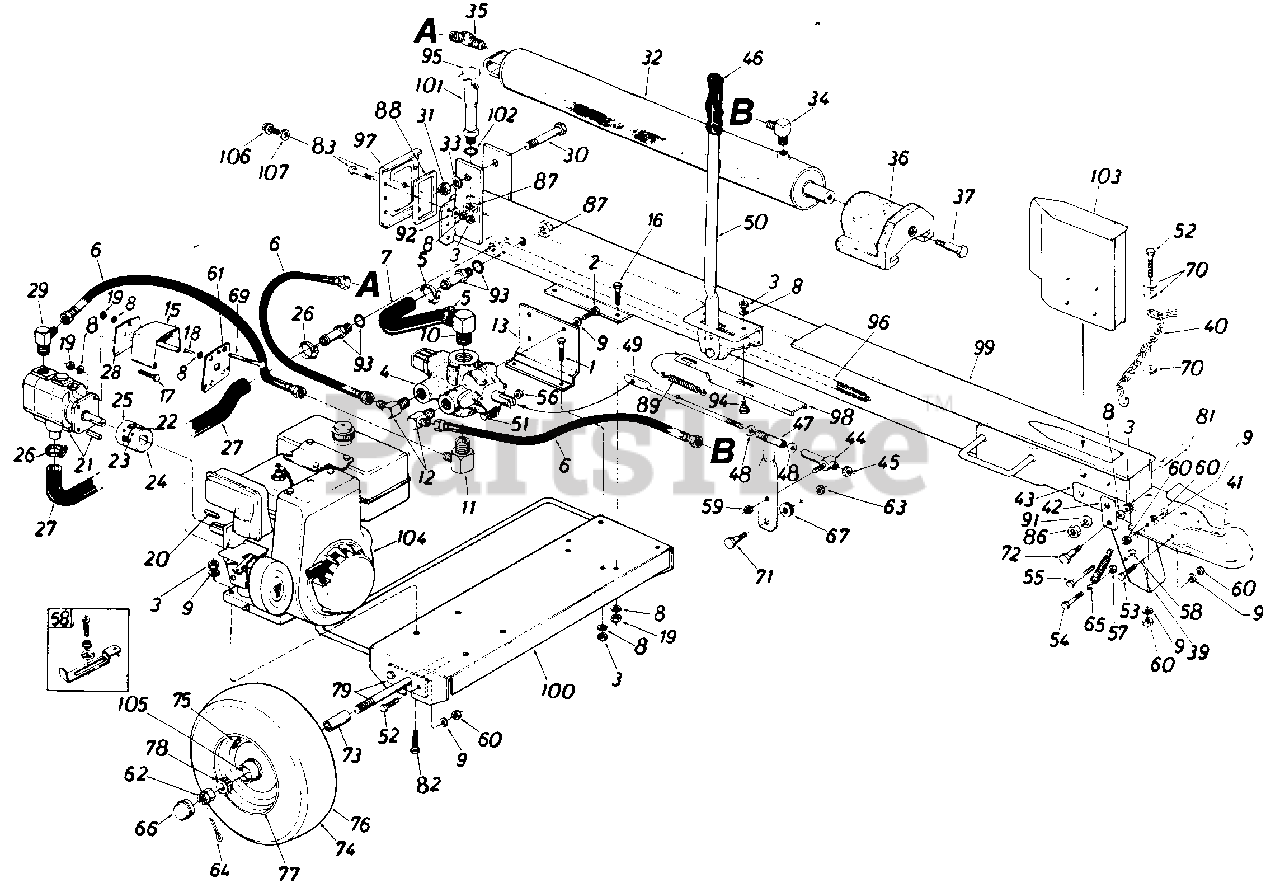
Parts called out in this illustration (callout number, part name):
1	Hex Bolt 5/16-18 x .75" Lg.
2	Hex Bolt 3/8-16 x .50" Lg.
3	Hex Nut 5/16-18 Thd.
4	Control Valve 400
5	Hose Clamp 5/8"
6	H igh Pressure Hose Ass'y. .38" I.D.
7	Return Hose-Valve to Tank 3/4" I.D.
8	L.-Wash. 5/16" I.D.
9	L.-Wash 3/8" I D.
10	Return Elbow
11	90ø Solid Male Adapter
12	90ø Solid Male Adapter
13	Valve Mtg. Plate
15	Coupling Shield
16	Hex Bolt 5/16-24 x 1.00" Lg.
17	Hex Bolt 5/16-24 x .75" Lg.
18	Hex Bolt 5/16-24 x .62" Lg.
19	Hex Nut 5/16-24 Thd.
20	Sq. Key 3/16" x 2.25" Lg.
21	PumP with Woodruff Key
22	Spider L-0-90
23	Set Scr. 1/4-20x .25" Cup
24	Coupling Half .75" I.D.
25	Coupling Half .50" I.D.
26	Hose Clamp 5/8"
27	Suction Hose 1.0" Dia.
29	90ø Solid Male Adapter
30	Hex Bolt 3/4" x 4.0" Lg.
31	Hex Nut 3/4" Thd.
32	Hydraulic Cylinder 3-1/2" Dia.
33	L.-Wash. 34" I.D.
34	High Pressure 90o Elbow
35	45ø Male Adapter 3/4-16 MJ-3/8-18 NP
36	Pusher Plate
37	Shoulder Bolt .62" Dia. x 4.75" Lg.
39	Flip Stand Bracket
40	Chain-Tovtl Hitch
41	Tow H itch Ass'y. Comp.
42	Stand Pivot Bracket
43	Tow Hitch Brk't. 2 x 3/16 10.25" Lg.
44	Ferrule Assy.
45	Hex Cent. L.-Nut 3/8-24 Thd.
46	Grip-Black Vinyl
47	Complession Spring
48	Special Washer .378 x 1.00" x .125 Thd. Lg.
49	Engagement Rod 3/8" Dia. x 9.0' Lg.
50	Engagement Handle
51	Hex Bolt 1/4-20 x 1.75" Lg.
52	Hex Bolt 3/8-24 x 1.25" Lg.
53	Hex Bolt 3/8-24 x .75" Lg.
54	Hex Bolt 1/4-28 x 1.00" Lg.
55	Hex Bolt 3/8-24 x 1.75" Lg. (Grade 5)
56	Hex Patch L.-Nut 1/4-20 Lg.
57	Hex Cent. L.-Nut 1/4-28 Thd.
58	Hex Nut 1/4-28 Thd.
59	Hex Cent. L.-Nut5/16-18 Thd.
60	Hex Nut 3/8-24 Thd.
62	Hex Castle Nut 3/4-16 Thd.
63	Hex L.-Nut 3/8-16 Thd.
64	Cotter Pin 5/32" Dia. x 1.25" Lg.
65	Extension Spring .50" O.D. 3.97" Lg.
66	Hub Cap
67	Rubber Washer
69	Hex Bolt 5/16-24 x 4.0" Lg.*
70	Fl.-Wash. .375" I.D. x .870" O.D. x .090
71	ShouIder Bolt .498" Dia. x .340" Lg.
72	Shoulder Bolt .437" Dia. x .268" Lg.
73	Spacer .75" I.D. x 1.12" O.D. x 1.56" Lg.
75	Air Valve-Tubeless
76	Tire Only 16.0 x 4.0-2 Ply
78	Roller Rearing 3/4" I.D.
79	Axle Ass'y. .75" Dia. x 36.25" Lg.
81	Hex Bolt 5/8-18 x 3.50" Lg.
82	Hex Bolt 5/16-24 x 1.75 Lg.
83	Hex Bolt 5/16-18 x 1.50" Lg.
86	Hex Nut 5/1-18 Thd
87	Hex Nut 11/16-12 Thd.
88	Gasket 2 62 5.12
89	Extension Spring .50 O.D. x 4.25" Lg.
91	L.-Wash.5/8" I.D.
92	Fl.-Wash. 34" 1 .D. x .68" O.D. x .062 Thk.
93	Adapter 1.0" Tube 11/16-12 " O "-R ing
94	Shoulder Bolt .437" Dia. x .180" Lg.
95	Breather Cap
96	Strainer Tube Ass'y.
97	End Plate
98	Engagement Brk't. 1.39 x 11.75 " Lg.
99	Complete Oil Tank Ass'y.
100	Engine Frame Ass'y.
101	Filler Tube Ass'y.
102	"O"-Ring 92" I.D. x 1.16" O.D. x .116 Dia.
103	Wedge Ass'y.
104	5 H.P. Enginel
105	Bearing Seal
106	Hex Hd. Tap Scr. 5/16"
107	Gasket
